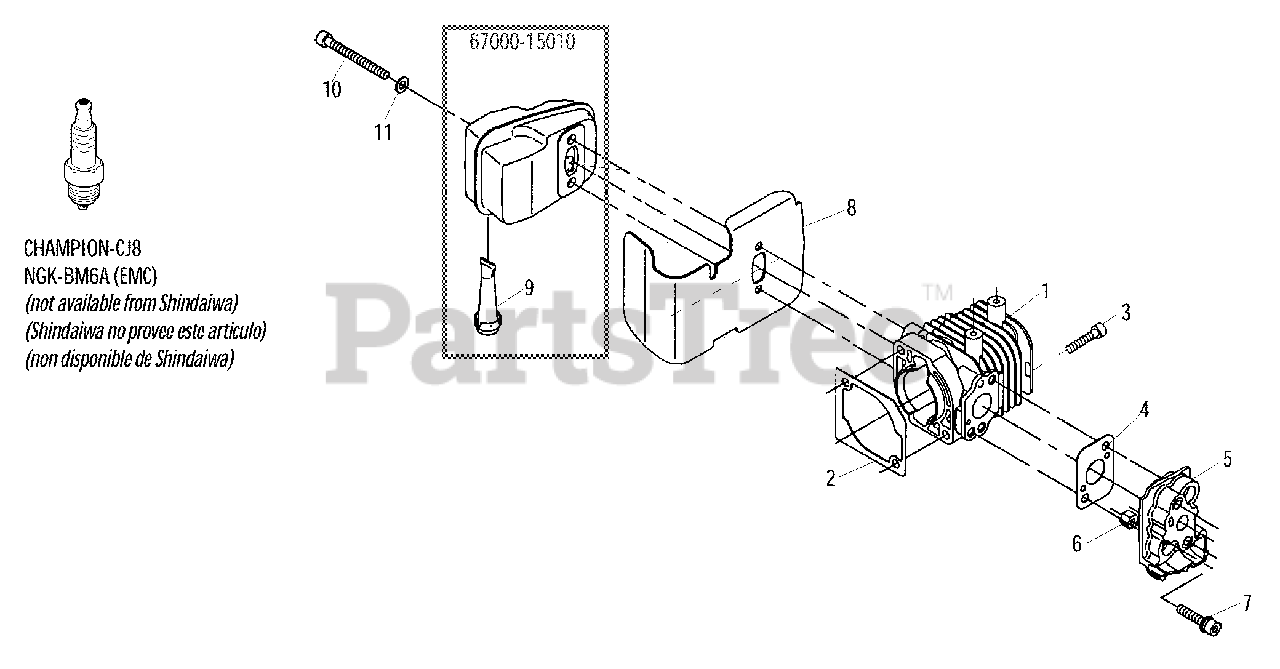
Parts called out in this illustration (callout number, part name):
1	CYLINDER
2	GASKET, CYLINDER
3	BOLT M5×25
4	GASKET
5	INSULATOR, INTAKE
6	NUT M5×6.3
7	BOLT M5×25
8	GASKET, EXHAUST
9	SCREEN, SPARK ARRESTER
10	BOLT 5×40
11	WASHER, FLAT 5.5×10×0.8
67000-15010	MUFFLER ASSY
